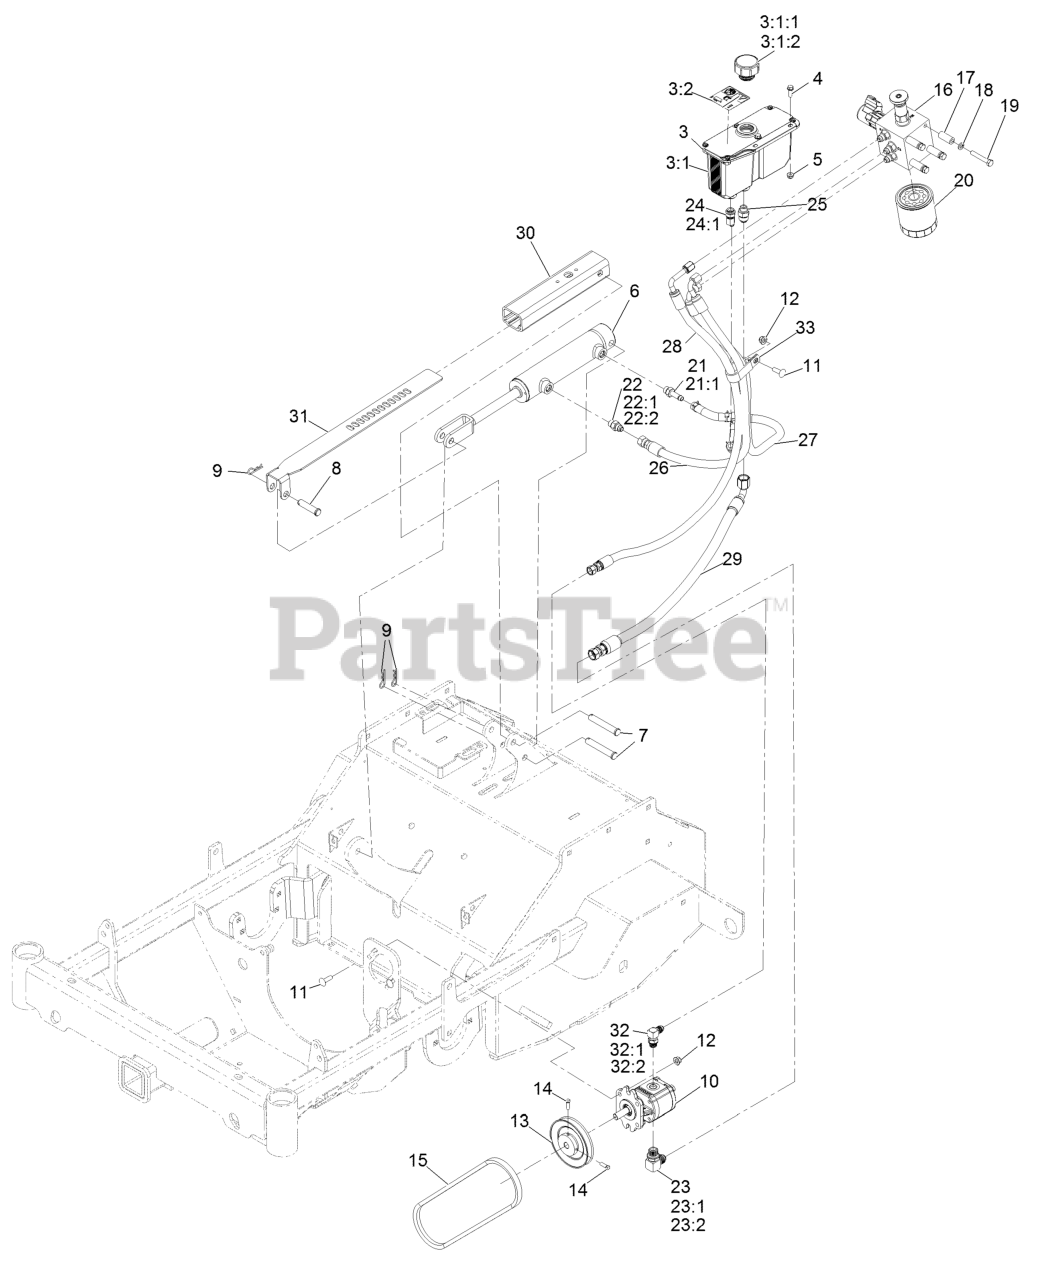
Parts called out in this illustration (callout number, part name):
3	Reservoir ASM
3:1	Reservoir-HYD
3:1:1	Cap-Reservoir, HYD
3:1:2	Gasket-Cap
3:2	Decal-Warning
4	Screw-Machine 1/4-20 X 3/4
5	Nut-Nyloc 1/4-20 Flg
6	Cylinder-Hydraulic
7	Pin-Clevis
8	Pin-Clevis
9	Pin-Hair
10	Pump-Hydraulic
11	Bolt-Carriage 5/16-18 X 1 Sp
12	Nut-Nyloc 5/16-18 Flg
14	Screw-SQH
16	Manifold ASM
18	Washer-Lock 5/16
19	Screw-HH 5/16-18 X 2
20	Element, Oil Filter
21:1	Adapter-Straight
22	O-Ring-SAE #6
22:1	O-Ring-37 Flare #6
22:2	Elbow-90deg
23	O-Ring-SAE #8
23:1	O-Ring-37 Flare #8
23:2	Fitting-Barbed, 45 DEG
24:1	Fitting-STR
25	Hydraulic Hose ASM
26	Hydraulic Hose ASM
27	Hydraulic Hose ASM
28	Hydraulic Hose ASM
29	Housing-Depth Control
30	Bracket-Depth Control
31	Adapter-90deg
32	O-Ring-SAE #6
32:1	O-Ring-37 Flare #6
32:2	Clamp-R, Double
33	Clamp-R, Double
